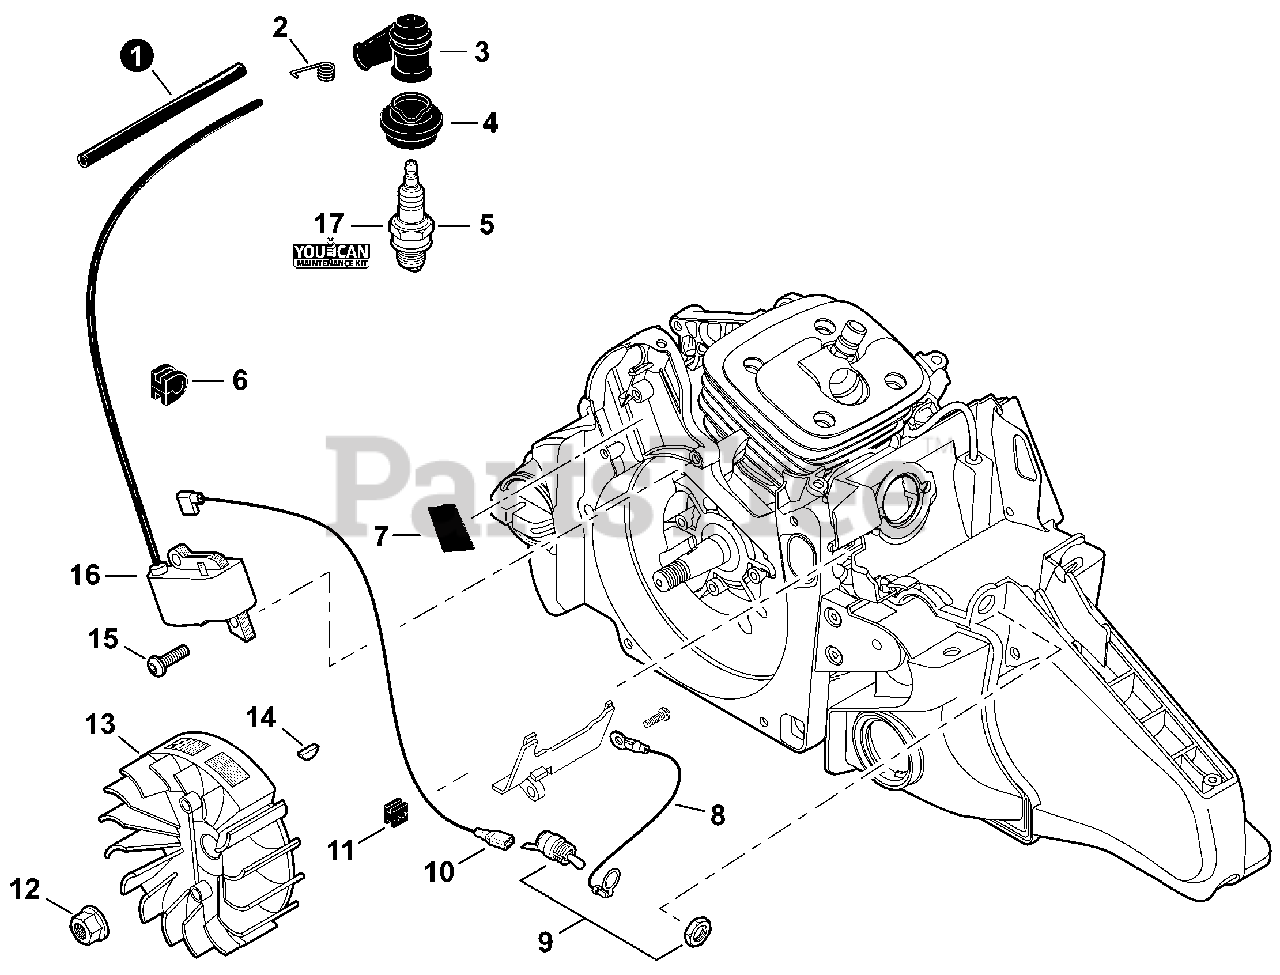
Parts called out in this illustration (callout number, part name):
1	TUBE, IGNITION COIL 6×7.2×70
2	TERMINAL, SPARK PLUG
3	CAP, SPARK PLUG
4	SEAL, SPARK PLUG
5	SPARK PLUG - BPMR8Y
7	CUSHION
8	LEAD - GROUND L= 170
9	SWITCH, ON-OFF
10	LEAD - IGNITION L= 280
11	GROMMET, LEAD
12	NUT, FLANGE M8
13	FLYWHEEL
14	KEY, WOODRUFF
15	BOLT, TORX 5×16
16	COIL, IGNITION
17	TUNE-UP KIT - YOUCAN™
